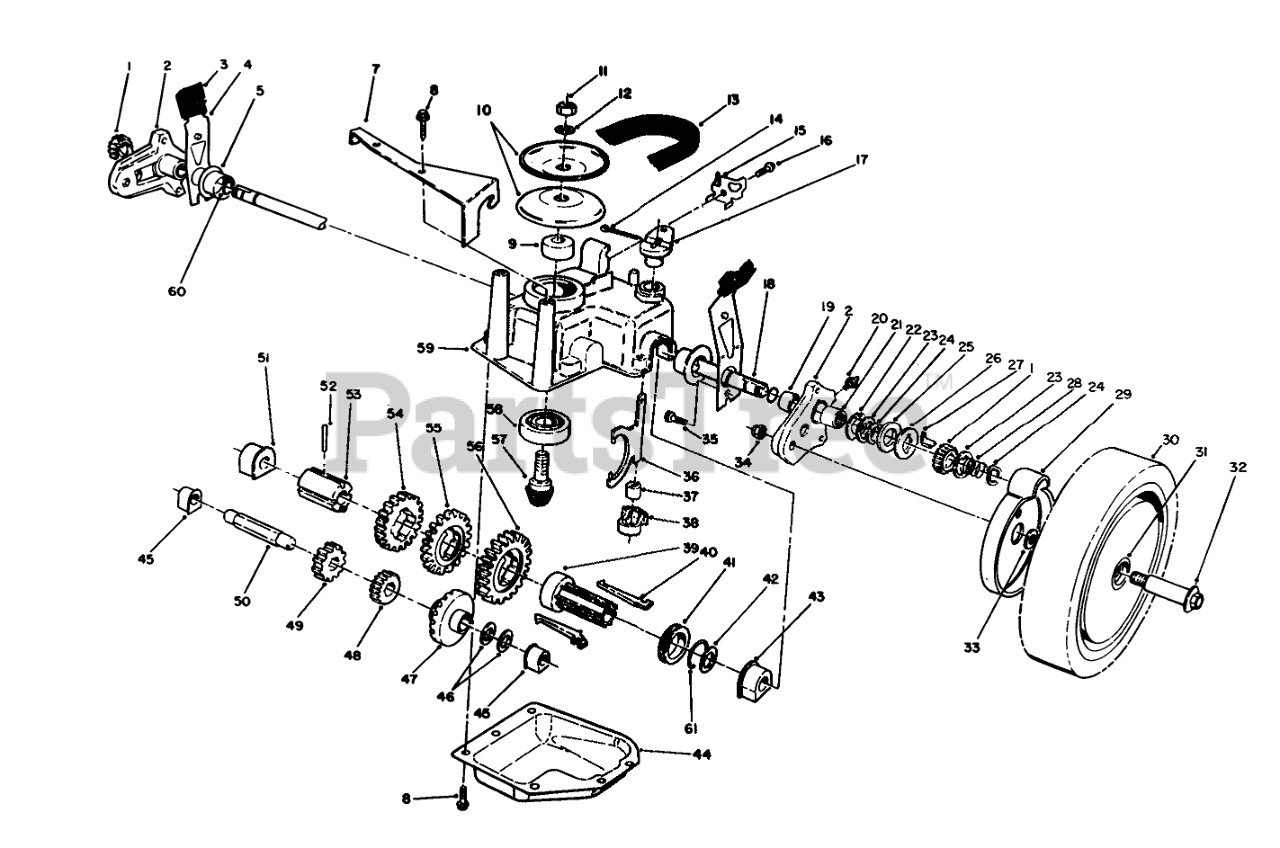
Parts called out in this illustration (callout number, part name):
1	GEAR-PINION
2	Pivot Arm Assembly (Incl. Ref #19, 20, & 21)
3	KNOB-ARM
4	SPRING ARM ASM SP
5	CAP-END
7	Bracket-Guide
8	SCREW-HWHTF
9	SPACER
10	Pulley Half
11	NUT-HEX
12	WASHER-FLAT
13	V-BELT E
14	PIN-COTTER
15	CLAMP-CABLE
16	SCREW-HWHTF
17	LEVER-SHIFT
18	SHAFT-OUTPUT
19	BUSHING
20	FITTING-GREASE
21	BEARING-ROLLER
22	WASHER-ARM, PIVOT
23	WASHER-THRUST, KEYED
24	RING-CLIP, LOCKING
25	RING-FRICTION
26	WASHER-CLUTCH
27	KEY-ROCKING, LH
28	SPRING-COMPRESSION
29	COVER-WHEEL
30	Wheel-Tire & Gear Ass-y (Incl. Ref . #31)
31	BUSHING
32	WHEEL BOLT
33	SPACER-COVER, WHEEL
34	Nut
35	SCREW-HWH
36	YOKE-SHIFT
37	BUSHING-YOKE
38	RETAINER-FORK, SHIFT
39	SLEEVE-KEY, SHIFT
40	KEY-SHIFT
41	COLLAR-SHIFT
42	WASHER-PLAIN
43	BUSHING-OUTPUT
44	Cover-Gearcase
45	BUSHING
46	WASHER-THRUST
47	Gear-Bevel
48	PINION-20T
49	PINION-25T
50	SHAFT-INTERMEDIATE
51	BUSHING
52	PIN-SPRING
53	SLEEVE-GEAR
54	GEAR-39T
55	GEAR-44T
56	GEAR-49T
57	Gear-Pinion
58	BEARING-BALL
59	CASE-GEAR, UPPER
60	O-RING
61	CLIP-SPRING
